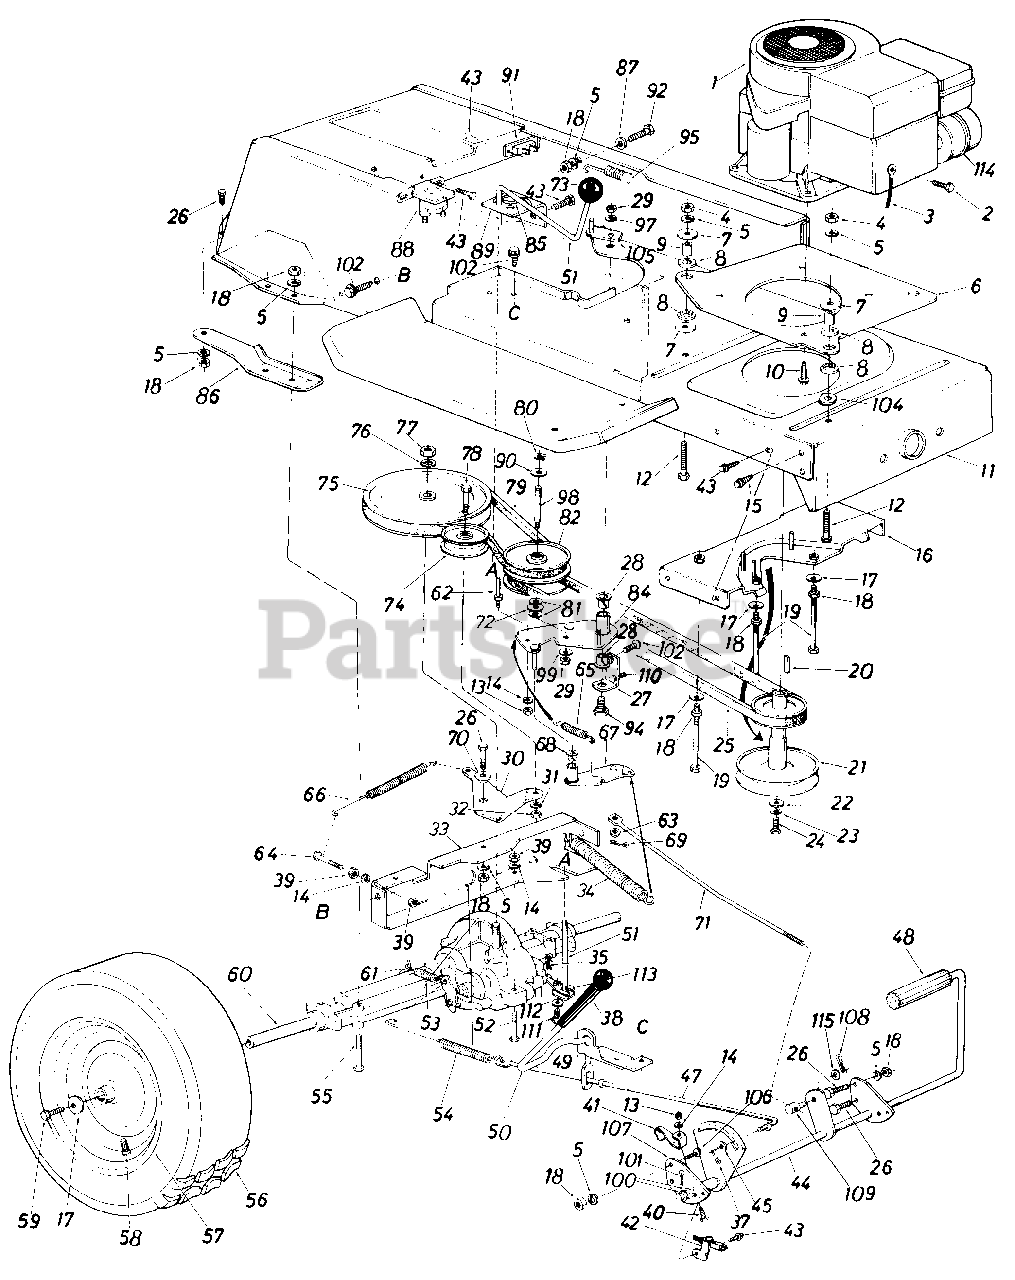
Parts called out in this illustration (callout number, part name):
1	Engine
2	Hex Bolt 1/4-20 x .62" Lg.
3	Electric Ground Wire
4	Hex Nut 5/16-24 Thd.
5	L-Wash. 5/16" I.D.
6	Engine Mounting Plate
7	Fl-Wash. .320" I.D. x 1.25"
8	Engine Mounting Grommet
9	.Spacer
10	Hex Bolt 3/8-16 x 1.25" Lg.
11	Lower Frame Ass'y.
12	Hex Bolt 5/16-24 x 1.25
13	Hex Nut 1/4-20 Thd.
14	L-Wash. 1/4" I.D.
15	Hex Wash. Hd. AB-Tap Scr. 5/16" x.75" Lg.
16	Belt Guard Brkt. Ass'y.
17	Bell-Wash. .345" I.D. x .88"
18	Hex Nut 5/16-18 Thd.
19	Hex Bolt 5/16-18 x 5.25" Lg.
20	Sq. Key 1/4" x 1/4" x 2.00"
21	Engine Pulley
22	Fl-Wash. 7/16" I.D. x 1.25"
23	L-Wash. 7/16" I.D.
24	Hex Bolt 7/16-20 x 1.50" Lg.
25	Variable-Speed Belt
26	Hex Bolt 5/16-18 x .75" Lg.
27	Bearing Shaft Bracket Ass'y.
28	Flanged Nyliner Brg. 5/8" I.D. x .88" Lg.
29	Hex Nut 3/8-24 Thd.
30	Idler Bracket
31	L-Wash. 3/8" I.D.
32	Hex Nut 3/8-24 Thd.
33	Transaxle Support Brkt.
34	Ext. Spring .94" O.D. x 6.7
35	Inter. Cott-Pin
37	Cotter Pin 3/32" Dia. x .75"
38	Grip Black
39	Hex Nut 1/4-28 Thd.
40	Hex Bolt 1/4-20 x 1.00" Lg.
41	Switch Actuator
42	Safety Switch
43	Hex Wash. Hd. S-Tap Scr. 1/4-20 x .50" Lg.
44	Clutch/Brake Pedal Ass'y.
45	Fl-Wash.
47	Brake Rod 20.9" Lg.
48	Foot Pad
49	Brake Lever Bracket
50	Hill Holder Brake Handle
51	Shift Lever Ass'y.
52	Hex Bolt 1/4-28 x 1.75" Lg.
53	Ext. Spring .38" O.D. x 2.5"
54	Ext. Spring .59" O.D. x 7.08"
55	Hex Bolt 5/16-18 x 2.75"
56	Wheel Ass'y. Comp.
57	Wheel Rim Only
58	Air Valve
59	Hex Bolt 5/16-24 x .75" Lg.
60	Transaxle Complete
61	Brake Return Spring Anchor
62	Belt Guard Pin 1/4-20 Thd.
63	Fl-Wash. .34" I.D. x .68" O.D.
64	Hex Bolt 1/4-28 x 1.25" Lg.
65	Ext. Spring
66	Ext. Spring .62" O.D. x 6.12"
67	Variable Speed Torque Brkt. Ass'y.
68	Flanged Bearing
69	Cotter Pin 3/32" Dia.
70	Shoulder Spacer .27" Lg.
71	Speed Control Link
72	Truss Bearing .56 Dia. x 1.25"
73	Ball Knob
74	Fl-Idler Pulley 3.25" x .75"
75	1/2" "V"-Pulley 8.0" O.D. x .501 " I.D.
76	L-Wash. 1/2" I.D.
77	Hex Jam Nut 1/2-20 Thd.
78	Hex Bolt 3/8-24 x 1.75" Lg.
79	Variable Speed Belt
80	Snap Ring .56" Dia.
81	Fl-Wash.
82	Variable Speed Pulley Ass'y. 5" O.D.
84	Variable Speed Brkt. Ass'y.
85	Comp. Spring Clip
86	Transaxle Support Brkt. R.H.
87	Fl-Wash. .34 I.D. x 1.12 O.D.
88	Solenoid
89	Shift Lever Bracket
90	Teflon Washer .565" I.D.
91	Circuit Breaker
92	Hex Bolt 5/16-18 x 1.50" Lg.
94	Shld. Bolt 3/8-24 x 3.12" Lg.
95	Ext. Spring .99" O.D. x 11"
97	Bell-Wash. .38" I.D. x .88"
98	Shaft .56" Dia. x 3.875" Lg.
99	Bell-Wash. .39" I.D. x 1.12"
100	Fl-Wash.
101	Cotter Pin 3/32" Dia. x 1.0"
102	Hex Wash. Hd. Scr. 5/16-18 x .62" Lg.
104	Fl-Wash. .32" I.D. x 1.25"
105	Belt Guard
106	Truss Mach. Scr. 5/16-18 x .75" Lg.
107	Pedal Bracket
108	Cotter Pin 3132" Dia. x .75"
109	Ferrule
110	Hex Bolt 5/16-18 x 1.0" Lg. (Gr. 5)
111	Hex Bolt 1/4-28 x .50" Lg.
112	Bell-Wash. .265" I.D. x .75"
113	Shift Lever Link Ass'y.
114	Muffler
115	Fl-Wash. .385" I.D. x .62" O.D.
